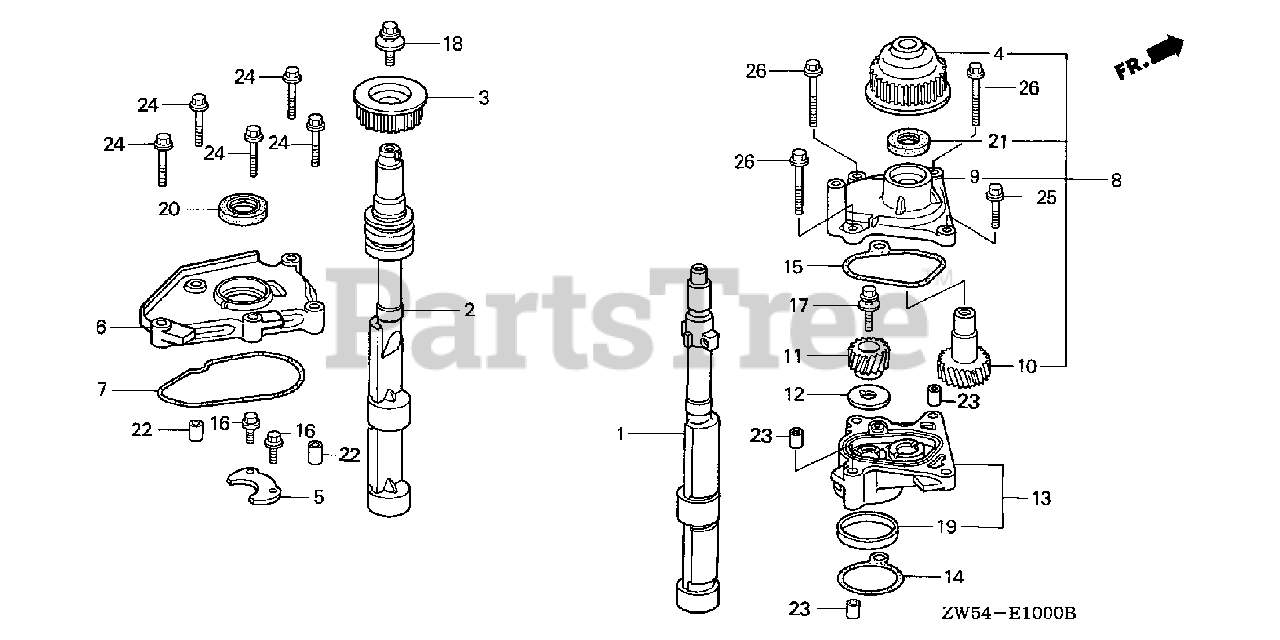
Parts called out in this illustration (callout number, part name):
1	SHAFT, RR. BALANCER
2	SHAFT, FR. BALANCER
3	PULLEY, BALANCER BELT DRIVEN (FR)
4	PULLEY, BALANCER BELT DRIVEN (RR)
5	METAL F, THRUST BALANCER SHAFT
6	COVER, BALANCER SHAFT
7	O-RING, BALANCER COVER
8	CASE, BALANCER GEAR
9	CASE, BALANCER GEAR
10	GEAR, BALANCER DRIVE
11	GEAR, BALANCER DRIVEN
12	WASHER, THRUST
13	SPACER, GEAR CASE
14	O-RING, GEAR CASE SPACER
15	GASKET B, OIL PUMP (ARAI)
16	BOLT, FLANGE (6X18)
17	BOLT-WASHER (8X33)
18	BOLT-WASHER (8X22)
19	PIN, DOWEL (49X10)
20	OIL SEAL (27X41X8) (NOK)
21	OIL SEAL (18X33X6)
22	PIN, DOWEL (8X14)
23	PIN, DOWEL (10X12)
24	BOLT, FLANGE (6X35)
25	BOLT, FLANGE (8X25)
26	BOLT, FLANGE (8X65)
